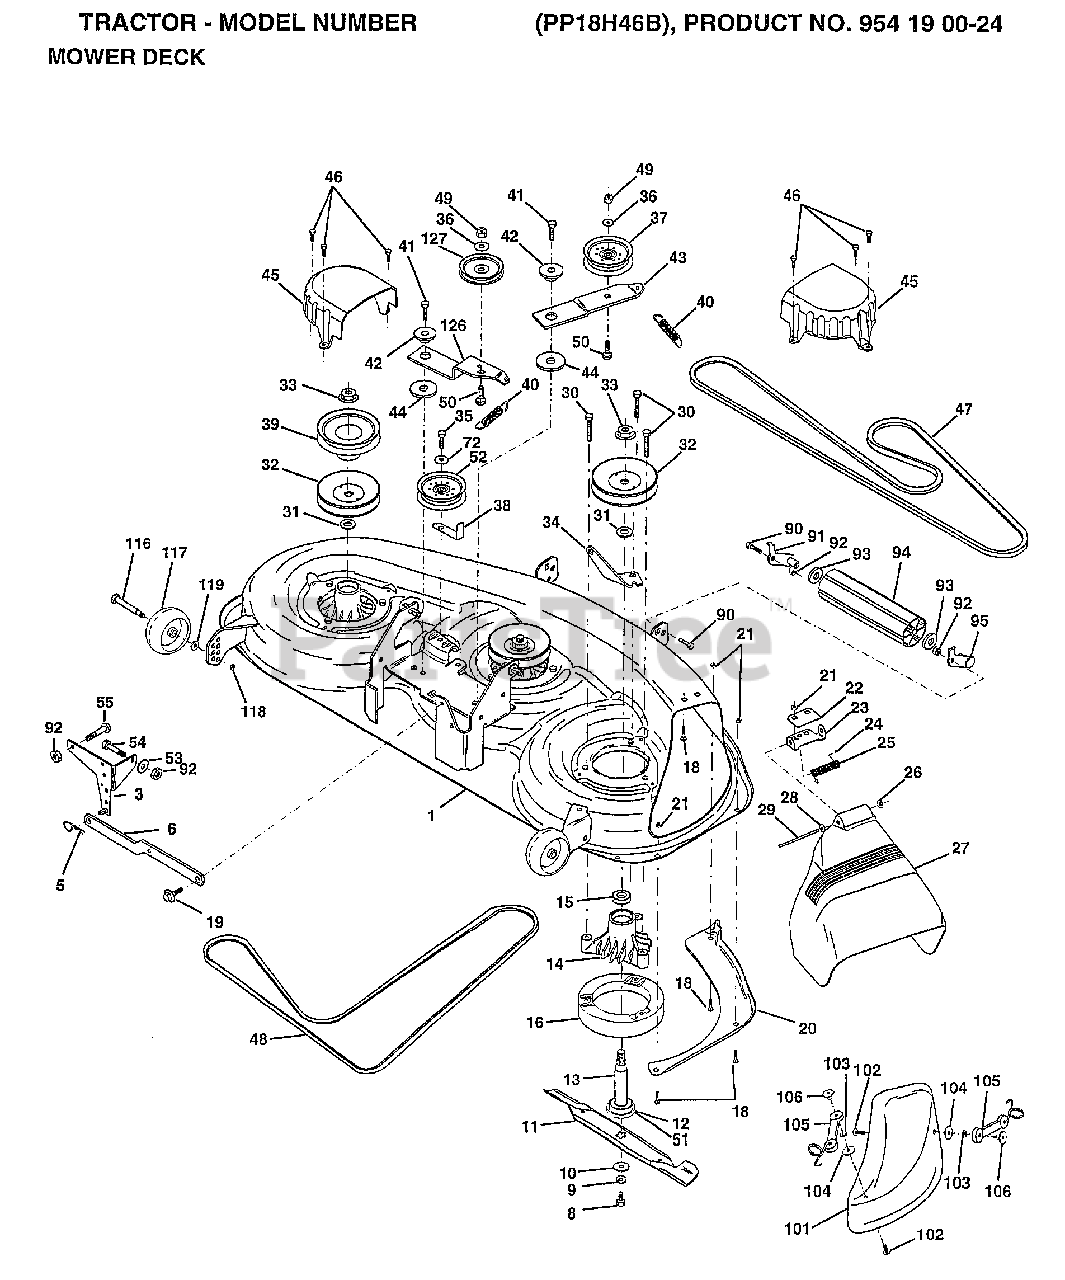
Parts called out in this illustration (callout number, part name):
1	"DECK.ASM.MOWER46"""
3	BRKT.ASM.SW.44/50
8	BLADE BOLT
10	WASHER.HARD.BLADE
11	"BLADE MULCH 46"""
12	BEARING.BALL
13	SHAFT.ASM.W/BRNG
14	HOUSING.MAND.44.V
15	BEARING
16	STRIPPER RND MWR
18	BOLT
19	BOLT SHD 5/16-18
20	BAFFFLE.VORTEX.46
22	STIFFENER BRKT
23	DEFLECTOR BRKT
24	CAP-SLEEVE LT
26	NUT PUSH M
27	SHIELD DEFLECTOR
28	WASHER
29	HINGE ROD
30	"SCREW-THD ROLL,WA"
31	WASHER
32	PULLEY.MAND.36/46
34	ANCHOR.SPRING.46
35	SCREW LT
36	WASHER
37	FLAT IDLER PULLEY
38	"KEEPER BELT,IDLER"
39	PULLEY.DRV.DCK.46
40	"SPRING.SEC.44""VEN"
41	SCREW
42	SPACER RETAINER
43	ARM.IDLER.DECK.46
44	HARDENED WASHER
45	COVER.MANDREL.46
46	SCREW.1/4-20X5/8
47	BELT-V.SEC.46.KEL
48	BELT V PRIM 50
50	BOLT.3/8-16X1.50
51	WASHER.FELT.
52	"PULLEY IDLER,FLAT"
53	WASHER
54	BOLT
72	WASHER HYT
90	BOLT
92	NUT
93	WASHER
101	COVER.MULCHING.
102	SCREW
103	LOCKWASHER
104	WASHER #10
105	LATCH ASSY.BAGGER
106	WELDNUT
116	BOLT.SHOULDER
117	WHEEL.GUAGE.MED.
118	LOCKNUT
119	WASHER
126	ARM.IDLER.PRIM.46
127	PULLEY.IDLER.4.25
